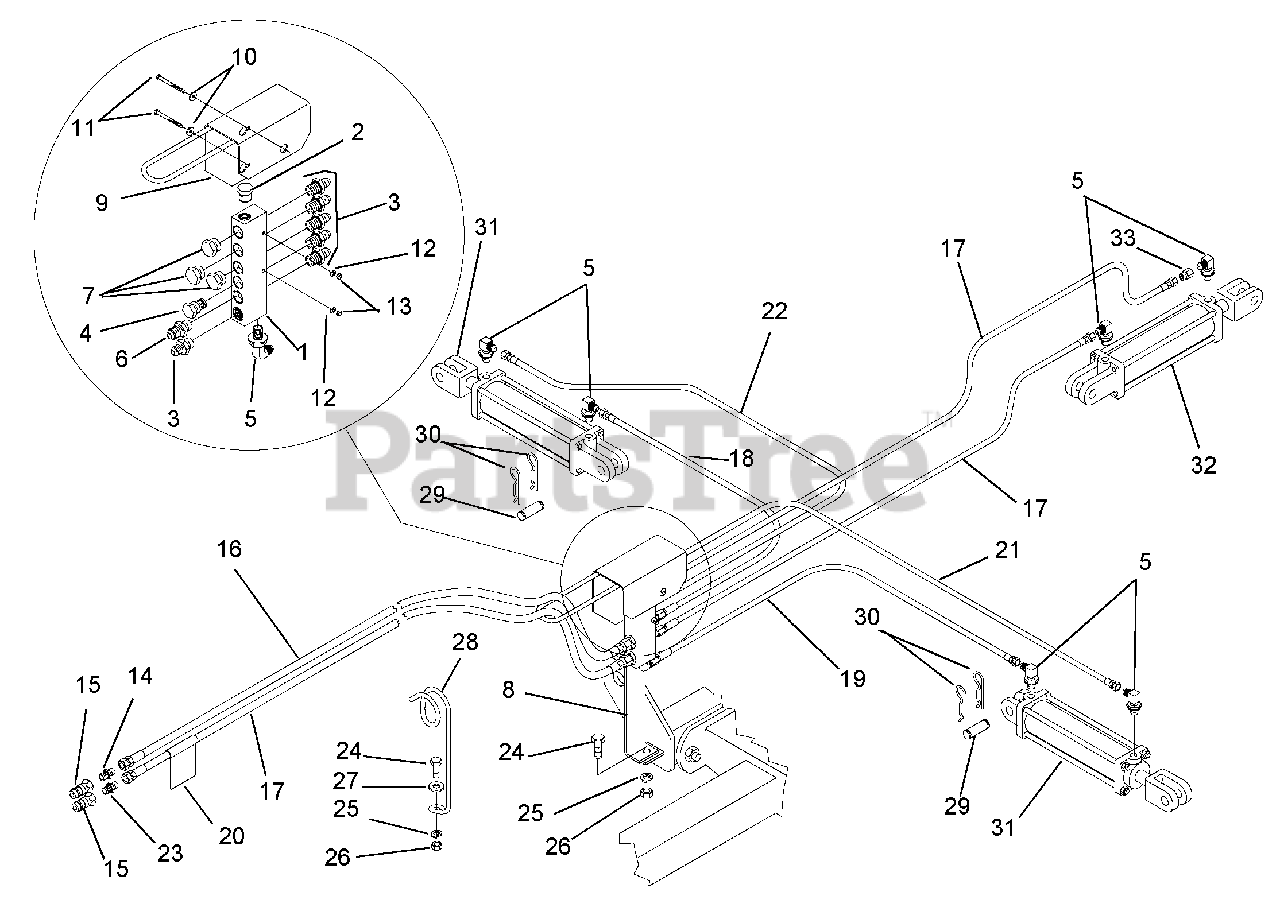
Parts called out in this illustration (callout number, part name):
1	Body, Valve
2	Plug, O-Ring Boss 9/16
3	Adapter, Hydraulic Fitting .75-16 SAE
4	Valve, Check
5	Elbow, 90-Degree
6	Adapter, Hydraulic Fitting .75-16 SAE
7	Assembly, Plug
8	Bracket, Valve
9	Weldment, Shield
10	Washer, Flat .25
11	Cap Screw, Hex Head .25-20 x 2.5
12	Washer, Lock .25
13	Nut, Serrated Flange .25-20
14	Adapter, Male Straight
15	Coupler .50 FNPT QD Male
16	Hose, Hydraulic 72-Inch
17	Assembly, Hydraulic Hose 72-Inch
18	Assembly, Hydraulic Hose
19	Hose, Hydraulic
20	Tag, Safety
21	Assembly, Hydraulic Hose
22	Assembly, Hydraulic Hose
23	Adapter, Male Straight
24	Cap Screw, Hex Head .625-11 x 1.75
25	Washer, Lock .625
26	Nut, Hex .625
27	Washer, Flat .625
28	Support, Hose
29	Pin, 1-Inch Diameter
30	Pin, Cotter .187 x 1.5
31	Cylinder, Hydraulic Wing 3 x 12" (see Deck-Lift Cylinders on page 52)
32	Cylinder, Hydraulic Rear 3 x 8" (see Deck-Lift Cylinders on page 52)
33	Union, Restrictor
